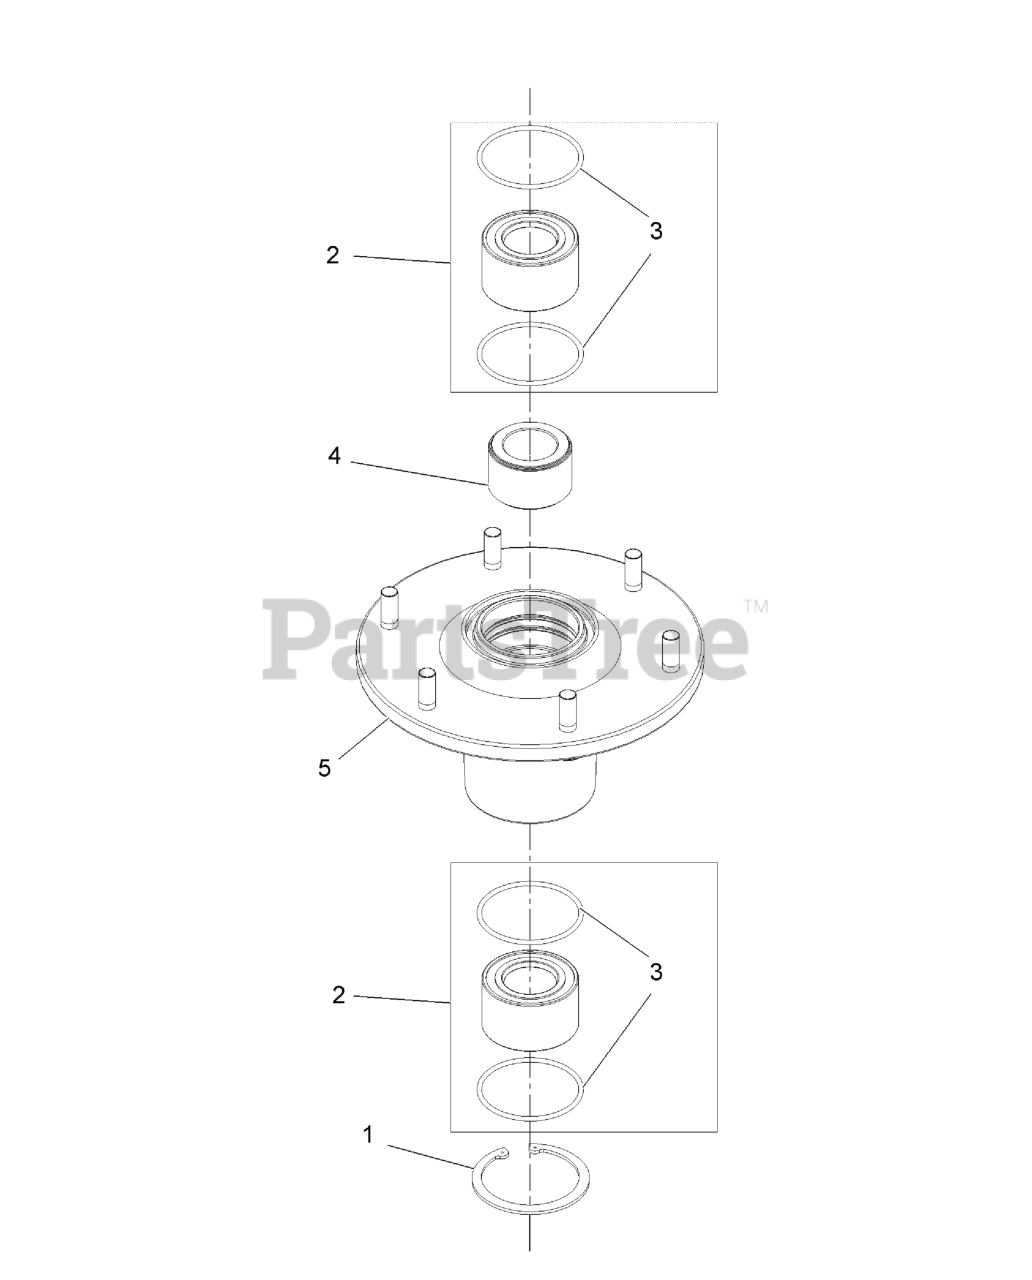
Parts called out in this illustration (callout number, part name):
1	RING-RETAINING
2	ASM, BEARING W/ORINGS
4	SPACER,BEARING
5	ASM,HOUSING W/STUDS
